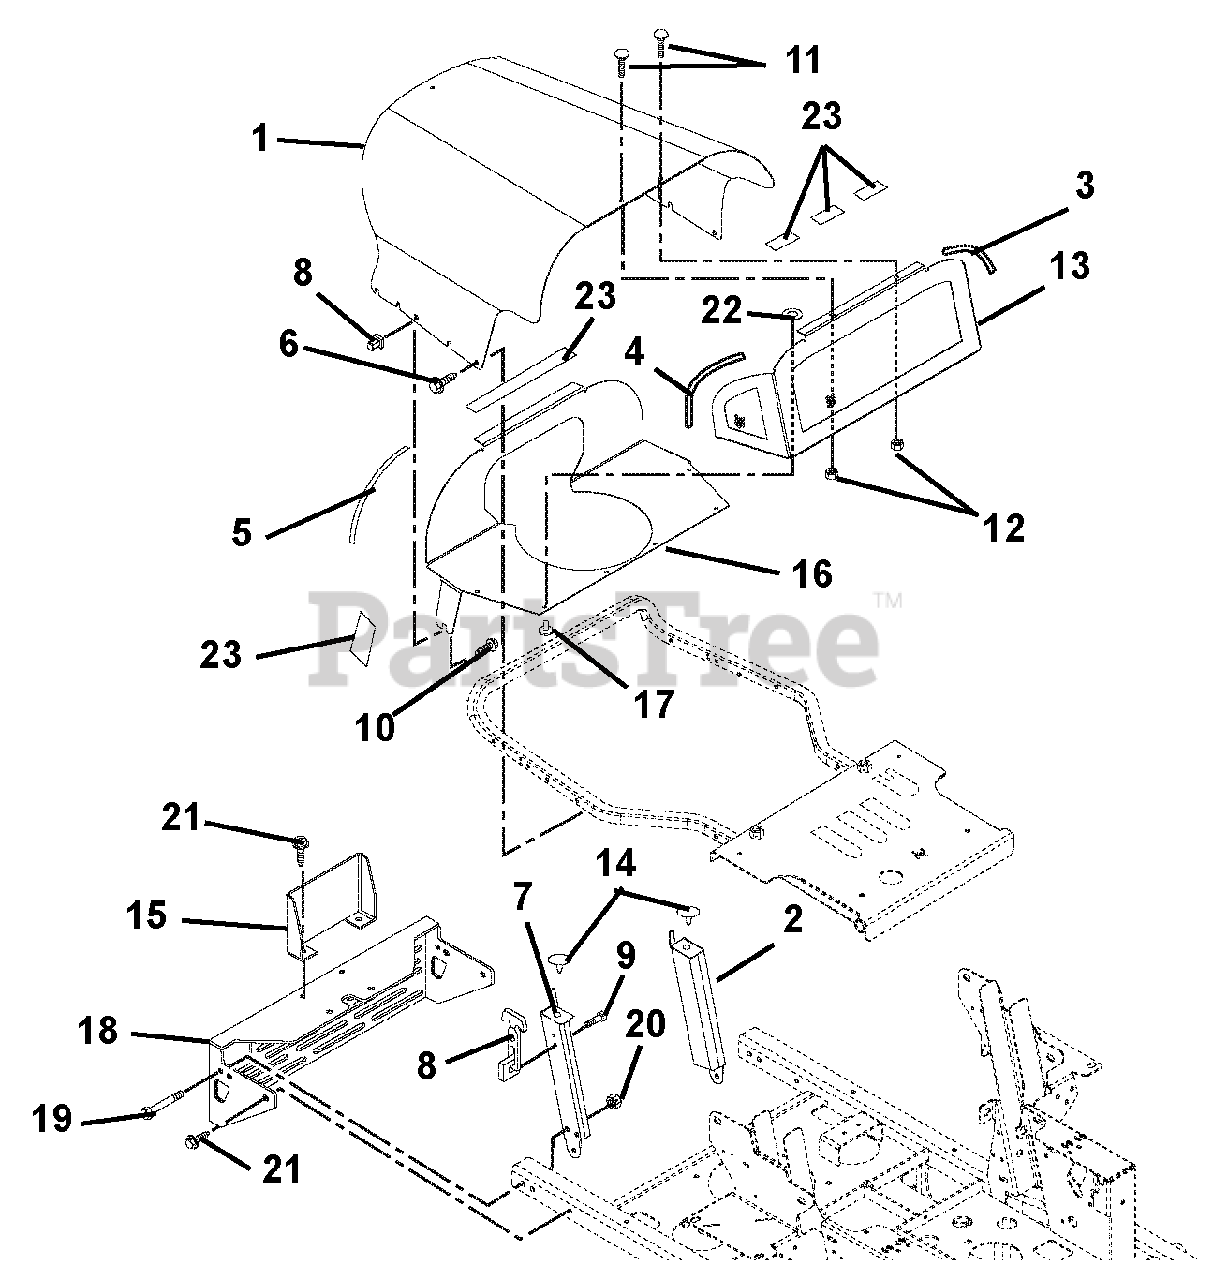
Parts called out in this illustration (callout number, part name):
2	Weldment, Hood Support, Left Hand
3	Seal, Trim Lok Bulk .06 Bubble
4	Seal, Trim Lok Bulk .06 Bubble
5	Seal, Trim Lok Bulk .06 Bubble (048, 069)
6	Screw, Tapping .38-16 x .50 Hex Washer Head
7	Weldment, Hood Support Right Hand
8	Latch, Rubber
9	Screw, Machine 10-24 x .50 Hex Washer Head
10	Screw, Machine 10-24 x 1.50 Hex Washer Head
11	Bolt-Round Head Square Neck .25-20 x .50 Grade 5
12	Nut-Locking-Top-Flange .25-20
13	Weldment, Plenum
14	Button Bumper
15	Guard, Muffler
16	Support, Plenum
17	Rivet, Pop .18 x .402
18	Bumper, Rear
19	Bolt, Hex .38-16 x 2.75 Grade 5
20	Nut-Locking-Top-Flange .38-16
21	Screw, Tapping .38-16 x .75 Hex Washer Head
22	Washer-Flat-Steel .219 x .50 x .049
23	VHB Tape 4941F
